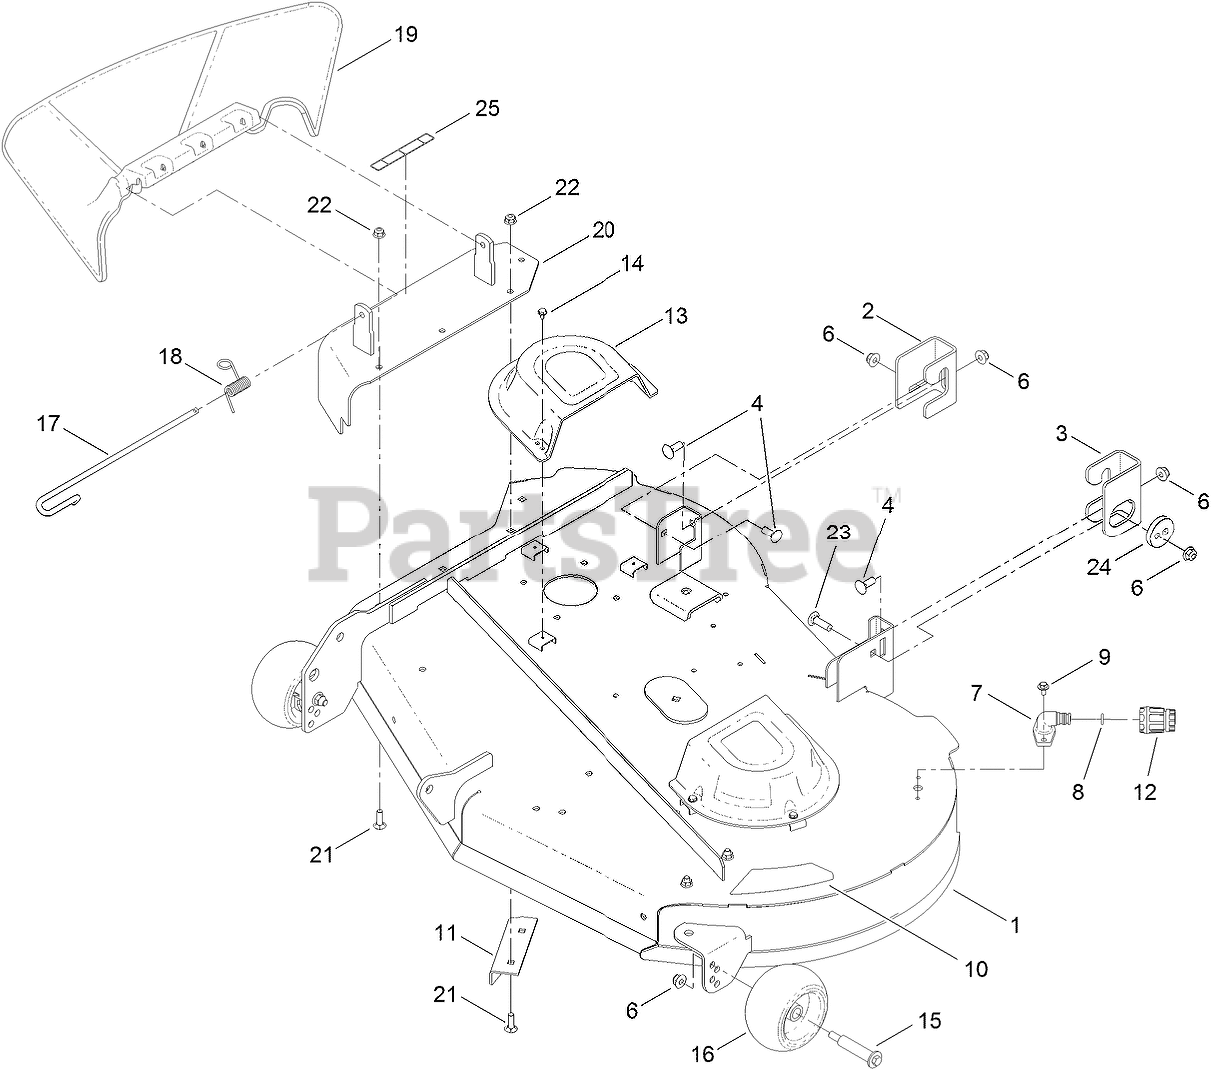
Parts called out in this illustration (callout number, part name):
1	42 INCH DECK AND DECAL ASM
2	BRACKET-HANGER, RH
3	BRACKET-HANGER, LH
4	BOLT-CARR
6	NUT-HF, NI
7	FITTING-WASHOUT
8	O-RING
9	SCREW-HHFTF
10	DECAL-DECK
11	BAFFLE-CUTOFF
12	CONNECTOR-HOSE
13	COVER-BELT
14	SCREW-HWHTF
15	BOLT-SHOULDER
16	ROLLER-SCALP, ANTI
17	PIN-CHUTE
18	SPRING-TORSION
19	DEFLECTOR-DISCHARGE
20	DISCHARGE COVER ASM
21	SCREW-CARR
22	NUT-HF, NI
23	SCREW-CARR
24	ECCENTRIC
25	DECAL-DANGER
